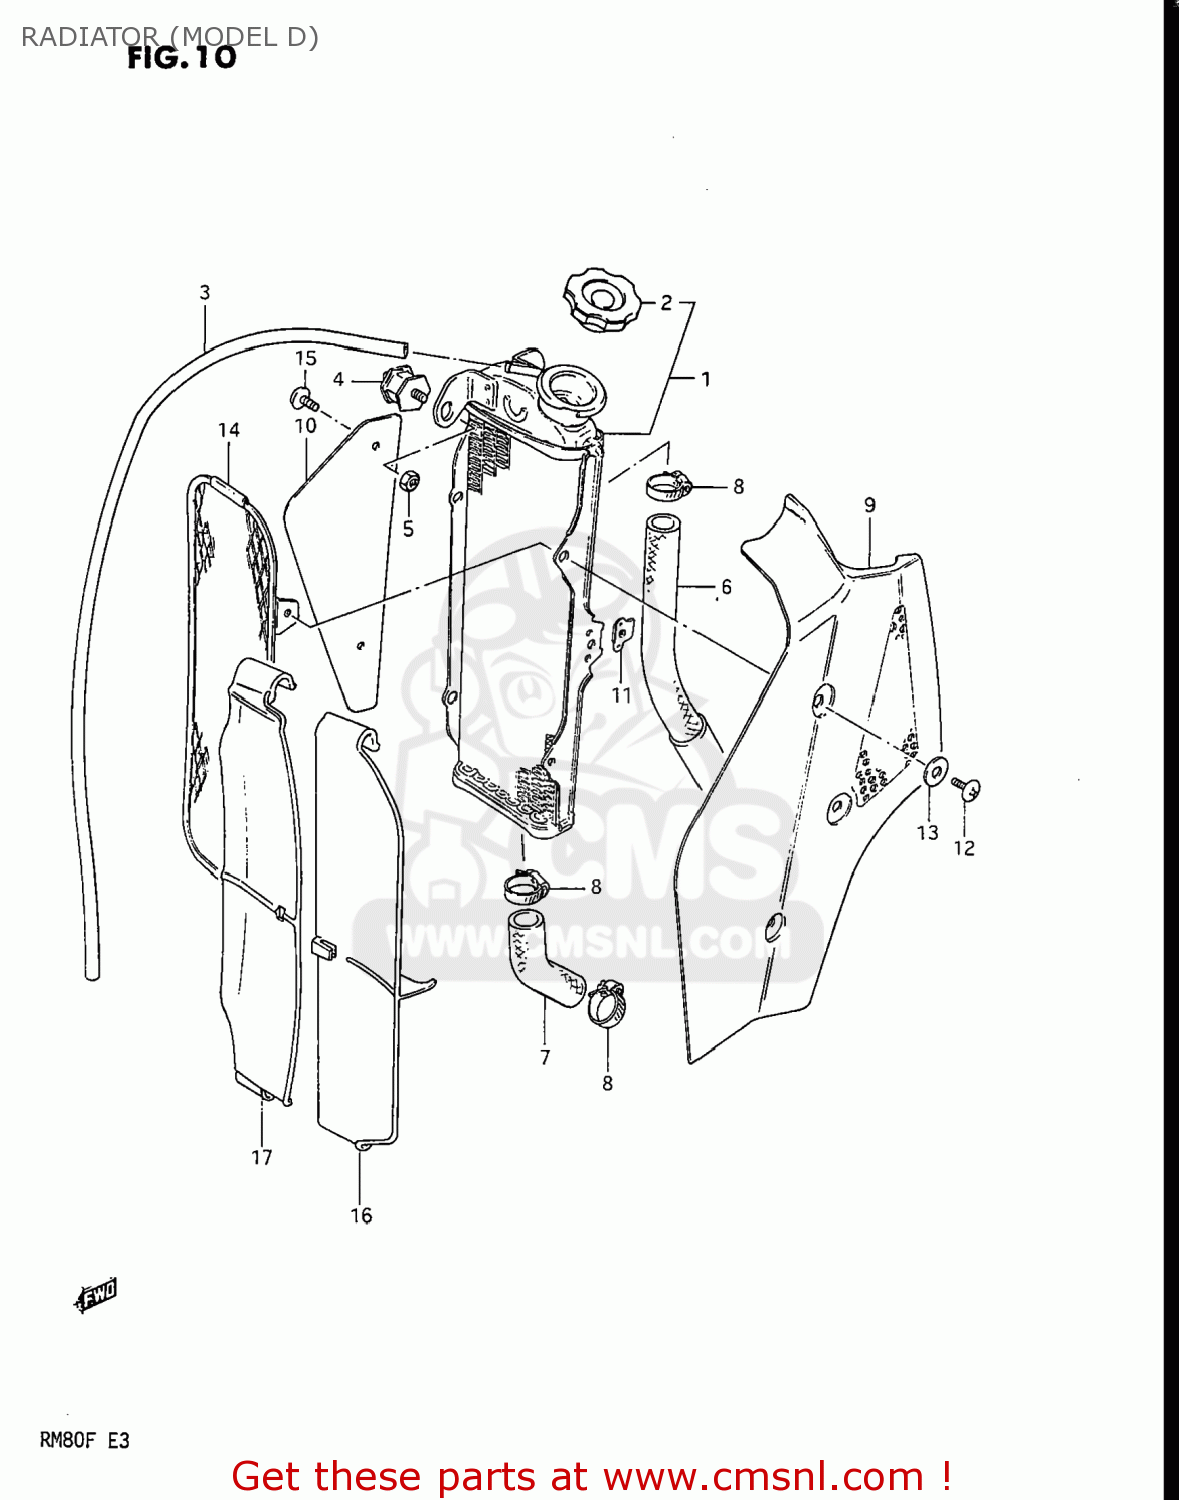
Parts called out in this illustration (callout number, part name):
1	RADIATOR ASSEMBLY,WATER
2	CAP,RADIATOR 1.1
3	HOSE,BREATHER
4	CUSHION,RADIATOR
5	NUT
6	HOSE,RADIATOR INLET
7	HOSE,RADIATOR OUTLET
8	CLAMP
9	COVER,RADIATOR,OUTER
10	COVER, INSIDE
11	PLATE,RADIATOR COVER F
12	SCREW M5X12 DIN 7985/N
13	WASHER(5.2X16X1)
14	BUMPER,RADIATOR
15	SCREW M5X12 DIN 7985/N
16	LOUVER,RADIATOR
17	LOUVER,RADIATOR
